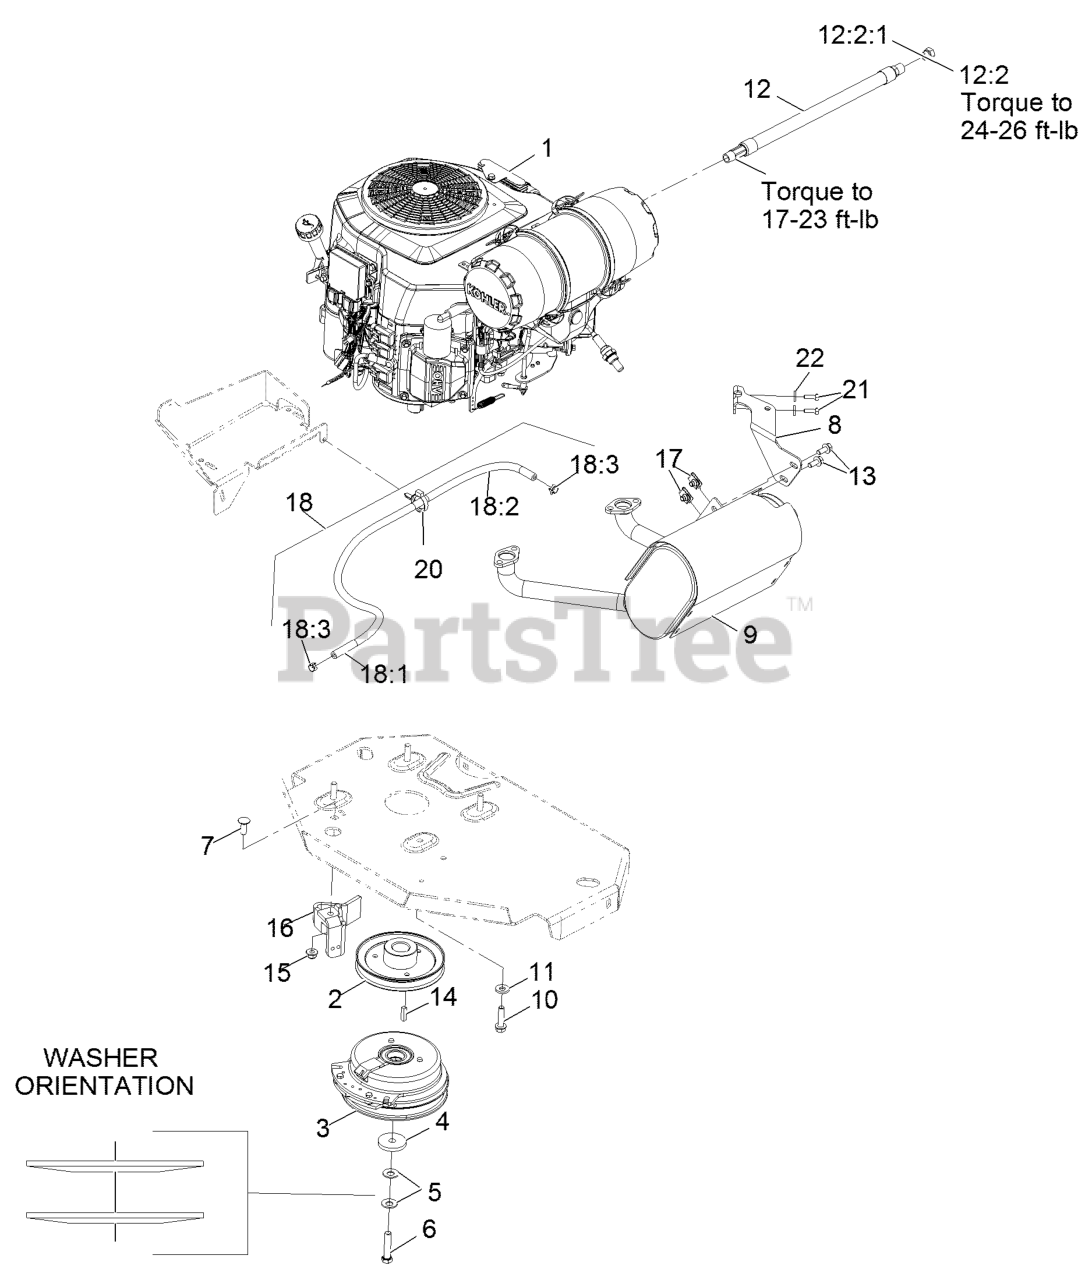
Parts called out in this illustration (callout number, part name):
1	Engine-Kohler
2	SHEAVE
3	CLUTCH KIT
4	WASHER-CLUTCH
5	WASHER-SPRING
6	SCREW-HH 7/16-20 X 1 1/2 W/LOCTITE
7	SCREW-CARR
8	MUFFLER BRACKET KIT
10	SCREW-HWH
11	WASHER-BELLEVILLE
12	OIL DRAIN HOSE ASM
12:2	PLUG-HH
12:2:1	O-RING
13	SCREW-HHF
15	NUT-HF, NI
16	CLUTCH-ANCHOR
18	FUEL LINE ASM
18:1	HOSE-FUEL
18:2	SLEEVE-THERMAL
18:3	CLAMP-HOSE
20	CLAMP-HOSE
21	SCREW-HH M6-1 X 20Mm W/Patch
22	WASHER-SPRING
